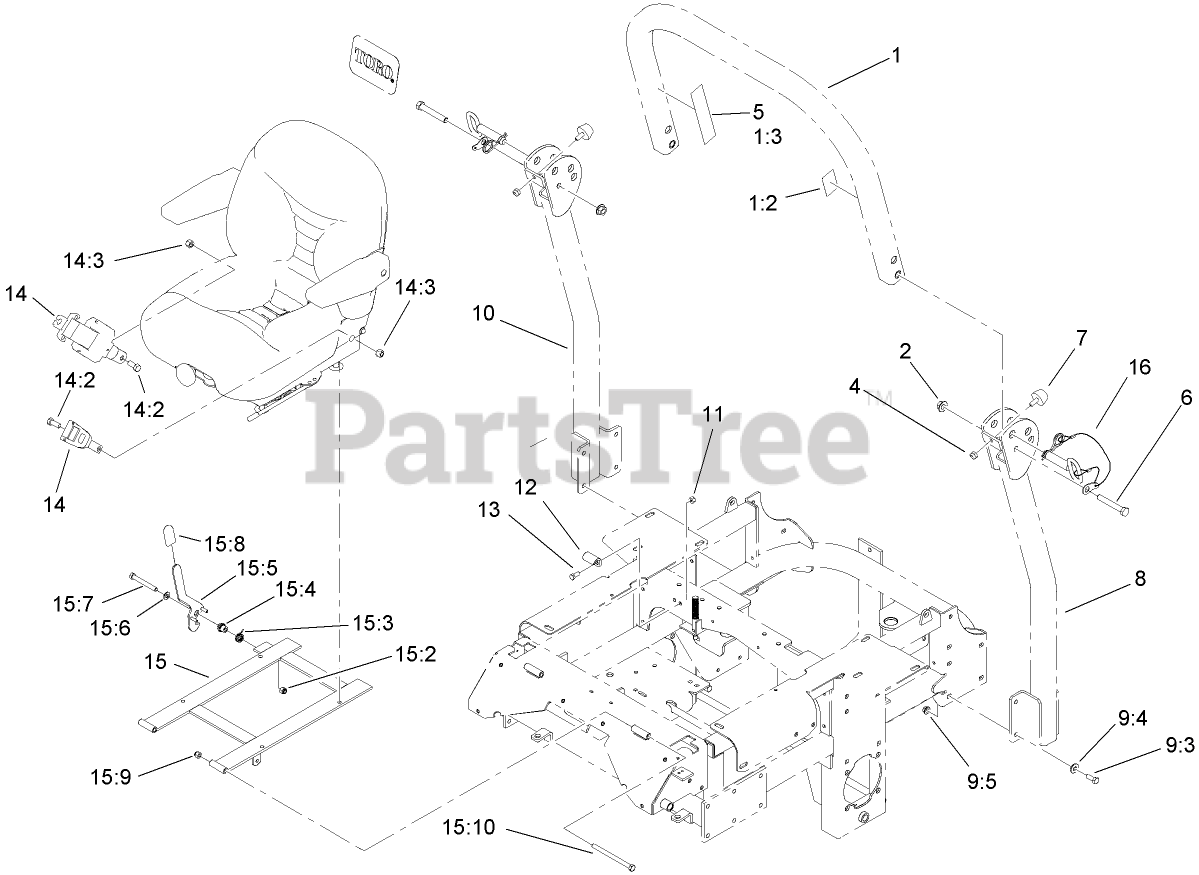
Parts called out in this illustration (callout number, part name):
1	Upper Tube ASM
1:2	DECAL-ROPS
1:3	DECAL-WARNING, FOLDING ROPS
2	NUT-HF
4	NUT-LOCK, NI
5	DECAL-WARNING
6	SCREW-HH
7	BUMPER-RUBBER
8	TUBE-SUPPORT, LH
9:3	SCREW-HH
9:4	WASHER-BELLEVILLE
9:5	NUT-HHF, WHIZ
10	TUBE-SUPPORT, RH
11	NUT-LOCK, NI
12	Catch-Latch, Seat
13	SCREW-HH
14	RETRACTABLE SEATBELT KIT
14:2	SCREW-HH
14:3	NUT-LOCK
15	SEATFRAME ASM
15:2	NUT-LOCK, NI
15:3	SPRING-TORSION
15:4	BUSHING-LATCH, SEAT
15:5	LATCH ASM
15:6	WASHER-FLAT
15:7	SCREW-HH
15:8	GRIP-LEVER
15:9	NUT-LOCK, NI
15:10	SCREW-HH
16	PIN-FOLD, ROPS
